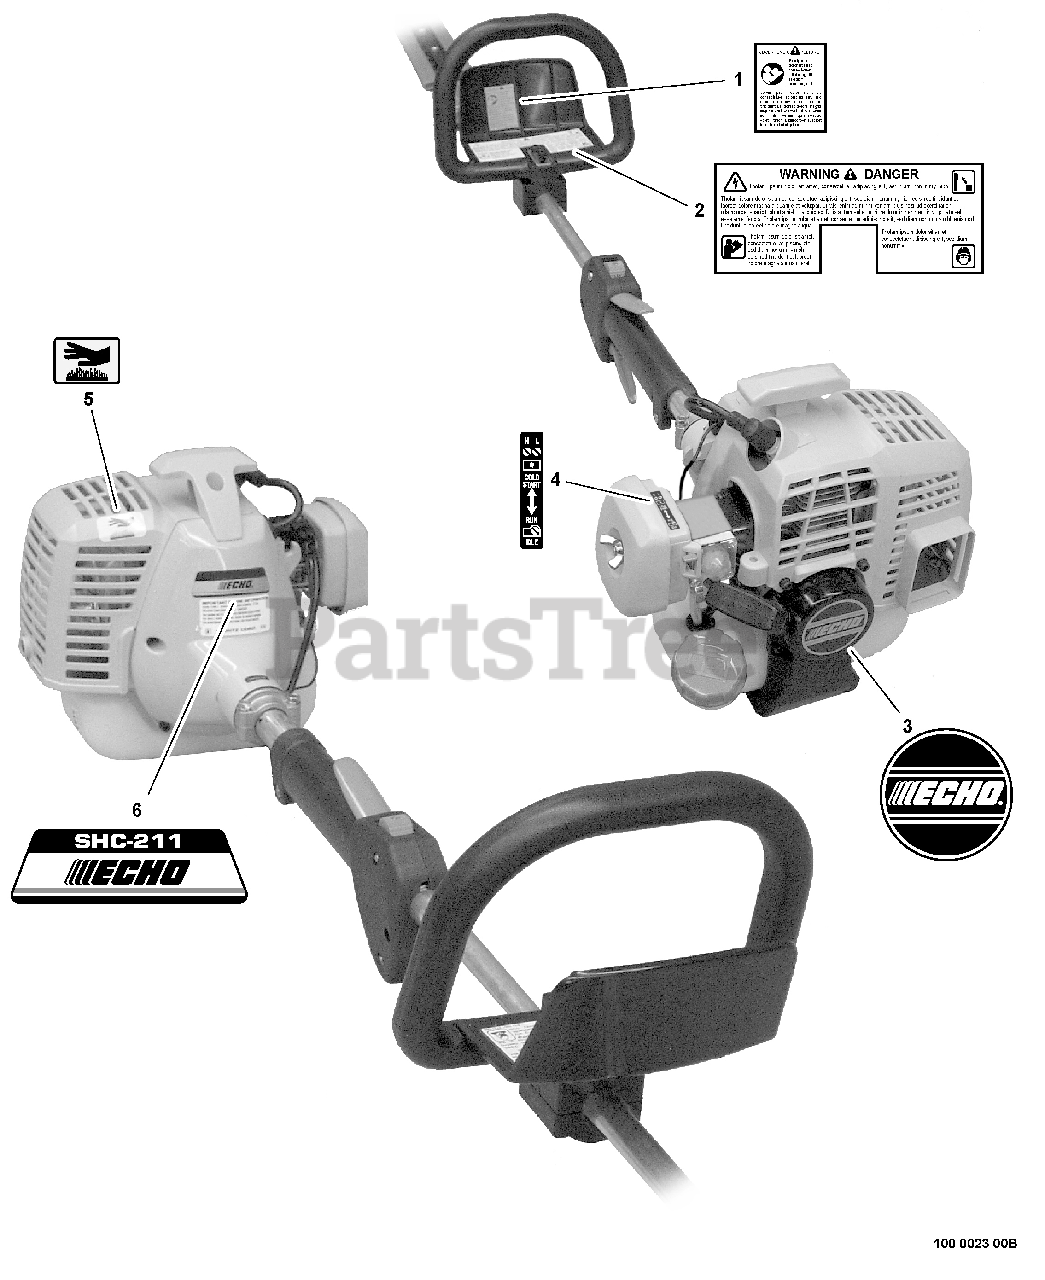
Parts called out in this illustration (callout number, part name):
1	LABEL - CAUTION -- SPANISH
2	LABEL - WARNING
3	LABEL - ECHO
4	LABEL - CHOKE
5	LABEL - HOT SURFACE
6	LABEL - MODEL SHC-211
